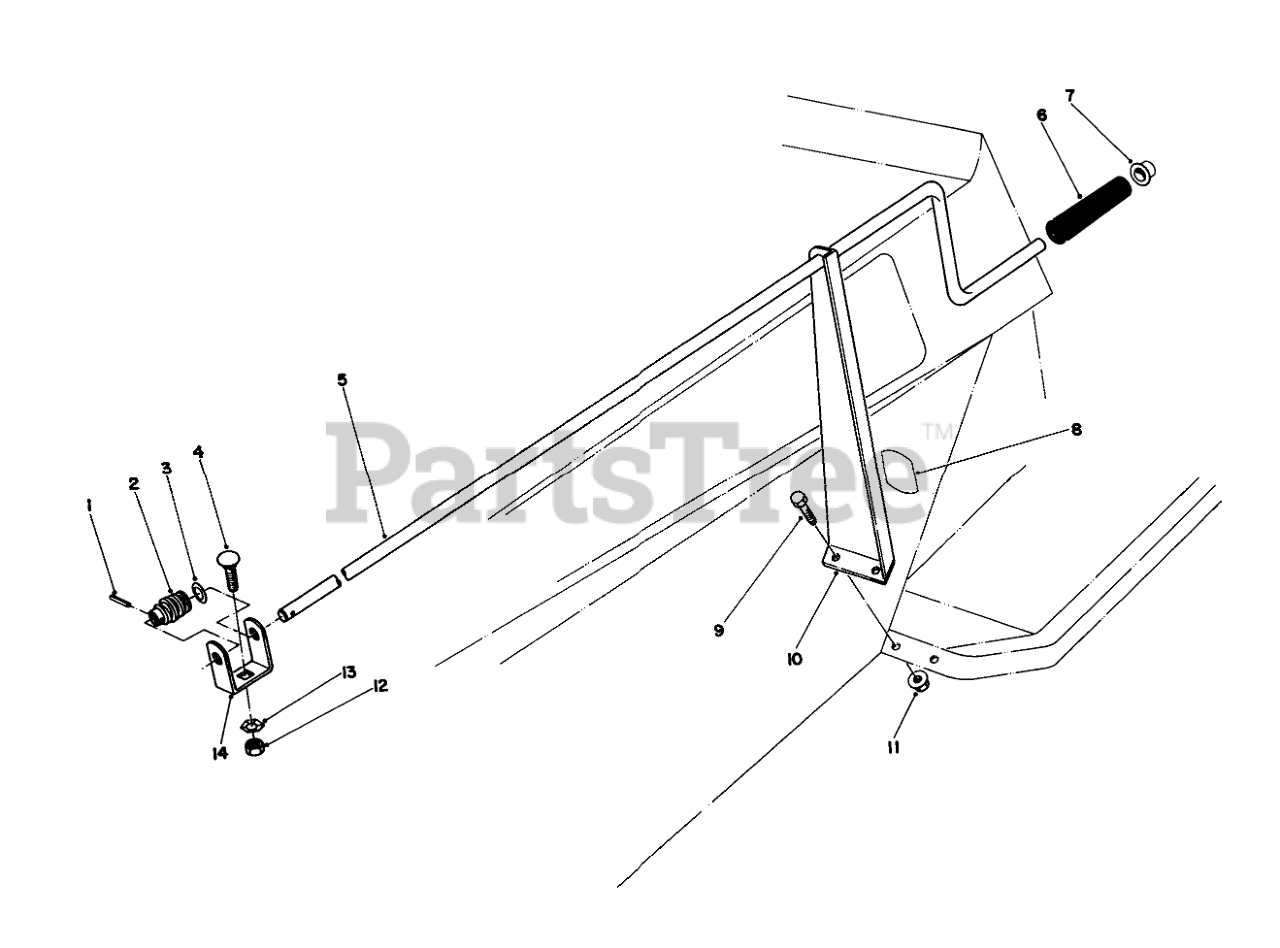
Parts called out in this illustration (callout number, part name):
1	PIN-SPRING
2	GEAR-WORM, CHUTE
3	WASHER-SPRING
4	BOLT-CARR
5	ROD-CHUTE CONTROL
6	GRIP-CONTROL, CHUTE
7	RETAINER-PUSH ON
8	CHUTE DECAL
9	SCREW-HH
10	CHUTE CONT BRKT B
11	NUT-HF
12	NUT-LOCK, NI
13	WASHER-LOCK
14	WORM BRKT B
